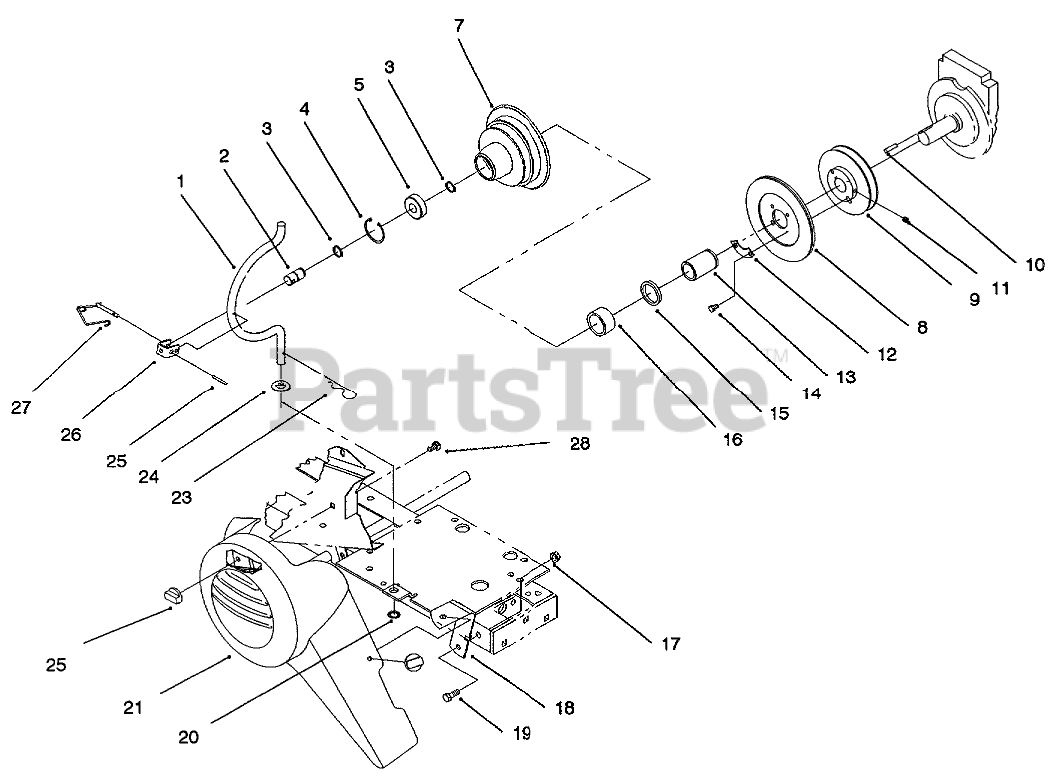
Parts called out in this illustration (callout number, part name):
1	ROD-HOUSING
2	SHAFT-PTO
3	Ring-Snap
4	RING-RETAINING
5	BEARING-BALL
7	Housing-Clutch
8	ASS'Y-CLUTCH PLATE
9	PULLEY
11	SCREW-SET, HSH
12	RETAINER
13	RACE-BEARING
14	SCREW-HEX HD CAP
15	SEAL-OIL
16	Seal
17	NUT-FLANGE
18	Bracket
19	SCREW-HH
20	RING-REINFORCED CIRC
21	GUARD - BELT
22	NUT - WING
23	PIN-COTTER, HAIR
24	WASHER-FLAT
26	CLEVIS
27	LOCKING PIN ASM
28	Retainer-Bolt
